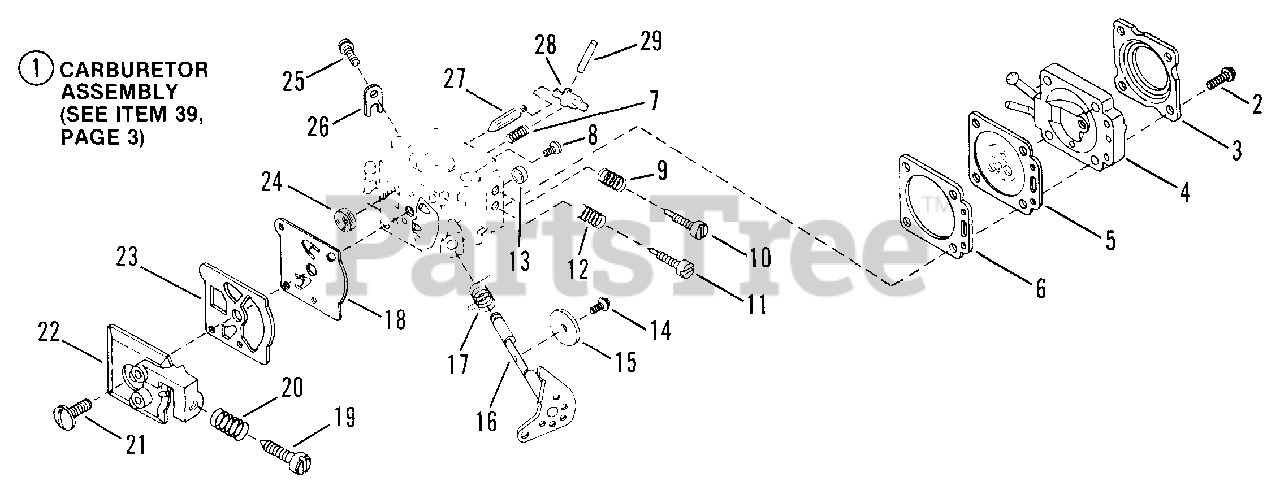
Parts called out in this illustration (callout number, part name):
1	ASSEMBLY, Carburetor
4	ASSEMBLY, Air Purge Body
5	ASSEMBLY, Diaphragm
7	SPRING, Lever
8	SCREW, Lever Pin
9	SPRING, Needle Adjustment
10	NEEDLE, High Speed
11	NEEDLE, Idle
12	SPRING, Needle Adjustment
13	PLUG, Welch
14	SCREW, Shutter
16	ASSEMBLY, Throttle Shaft
17	SPRING, Throttle Return
18	DIAPHRAGM, Pump
19	SCREW, Idle Adjustment
20	SPRING, Idle Adjustment
21	SCREW, Pump Cover
22	COVER, Pump
23	GASKET, Pump
24	SCREEN, Inlet
25	SCREW, Throttle Lever
26	CLIP, Throttle Lever
27	VALVE, Inlet
28	LEVER, Metering
29	PIN, Lever
